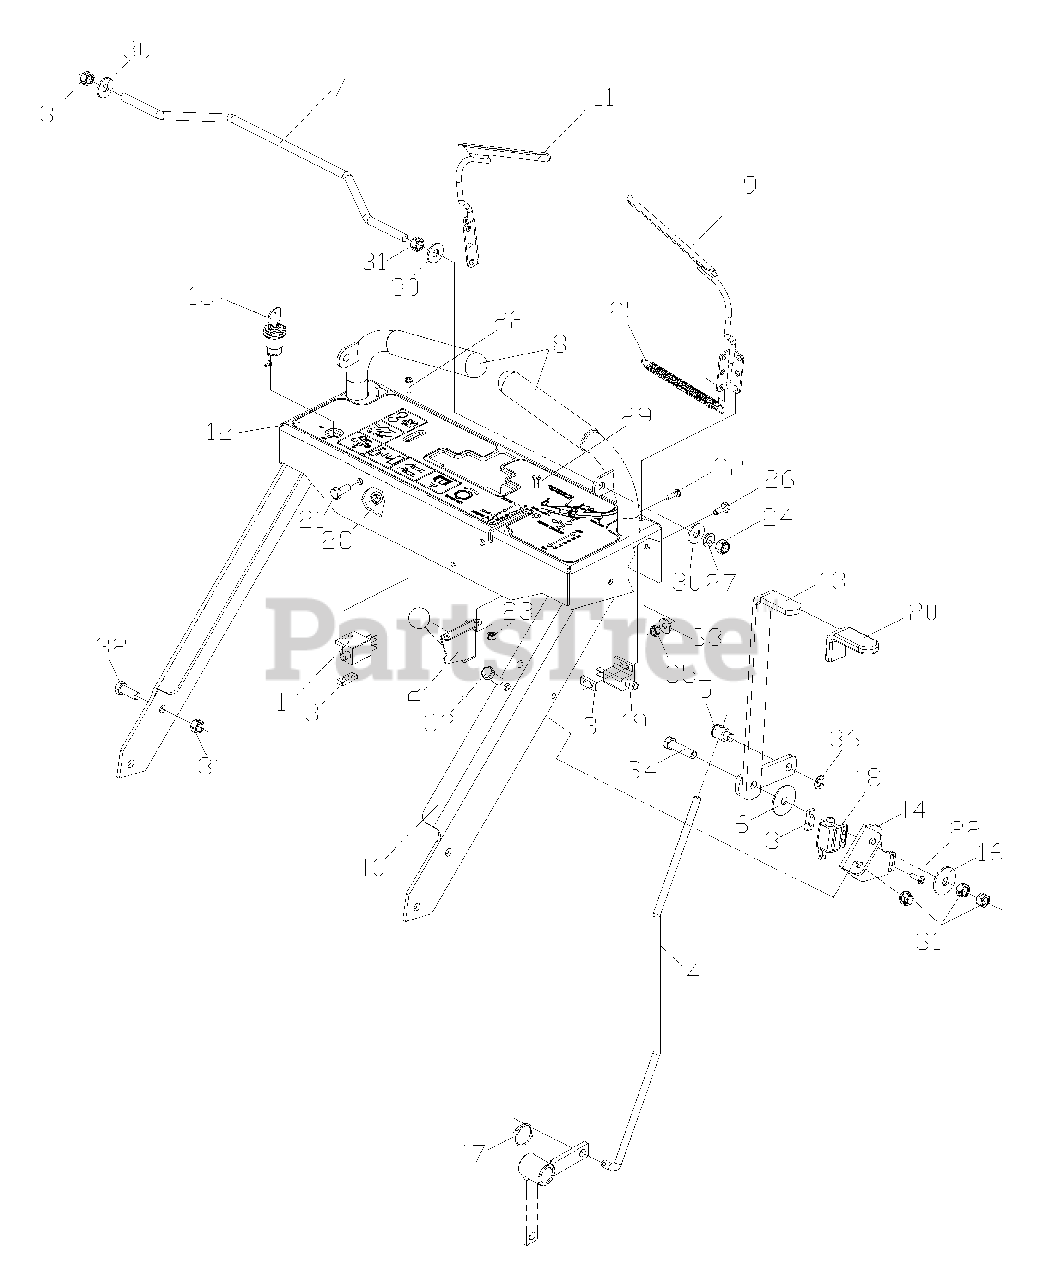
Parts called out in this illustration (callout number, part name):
1	SWITCH N.C.
2	THROTTLE CABLE
3	TAPPED PLATE
4	BLADE LINKAGE
6	WASHER, FRICTION
7	NEUTRAL BAIL
9	OP LEVER, LEFT
10	HANDLE W/DECALS
11	OP LEVER, RIGHT
12	DECAL, CONSOLE
13	BLADE ENGAGE LEVER
14	BLADE ENGAGE BRKT.
15	KEY SWITCH
16	WASHER, CONE
19	SWITCH N.C.
21	HCS 5/16 X 750
22	SCREW #10 X 625
23	NUT #10 NYLOC
24	NUT 3/8 NYLOC
26	HCS 1/4 X 625
27	WASHER 3/8 LOCK
28	NUT 3/8 CTR. LOCK
29	SCREW #10 X 500
30	WASHER 3/8 FLAT
31	NUT 3/8 CTR. LOCK
32	HCS 3/8 X 1.00
33	WASHER 1/4 FLAT
34	HCS 3/8 X 1.500
35	NUT 1/4 CTR. LOCK
37	DECAL, ETS
